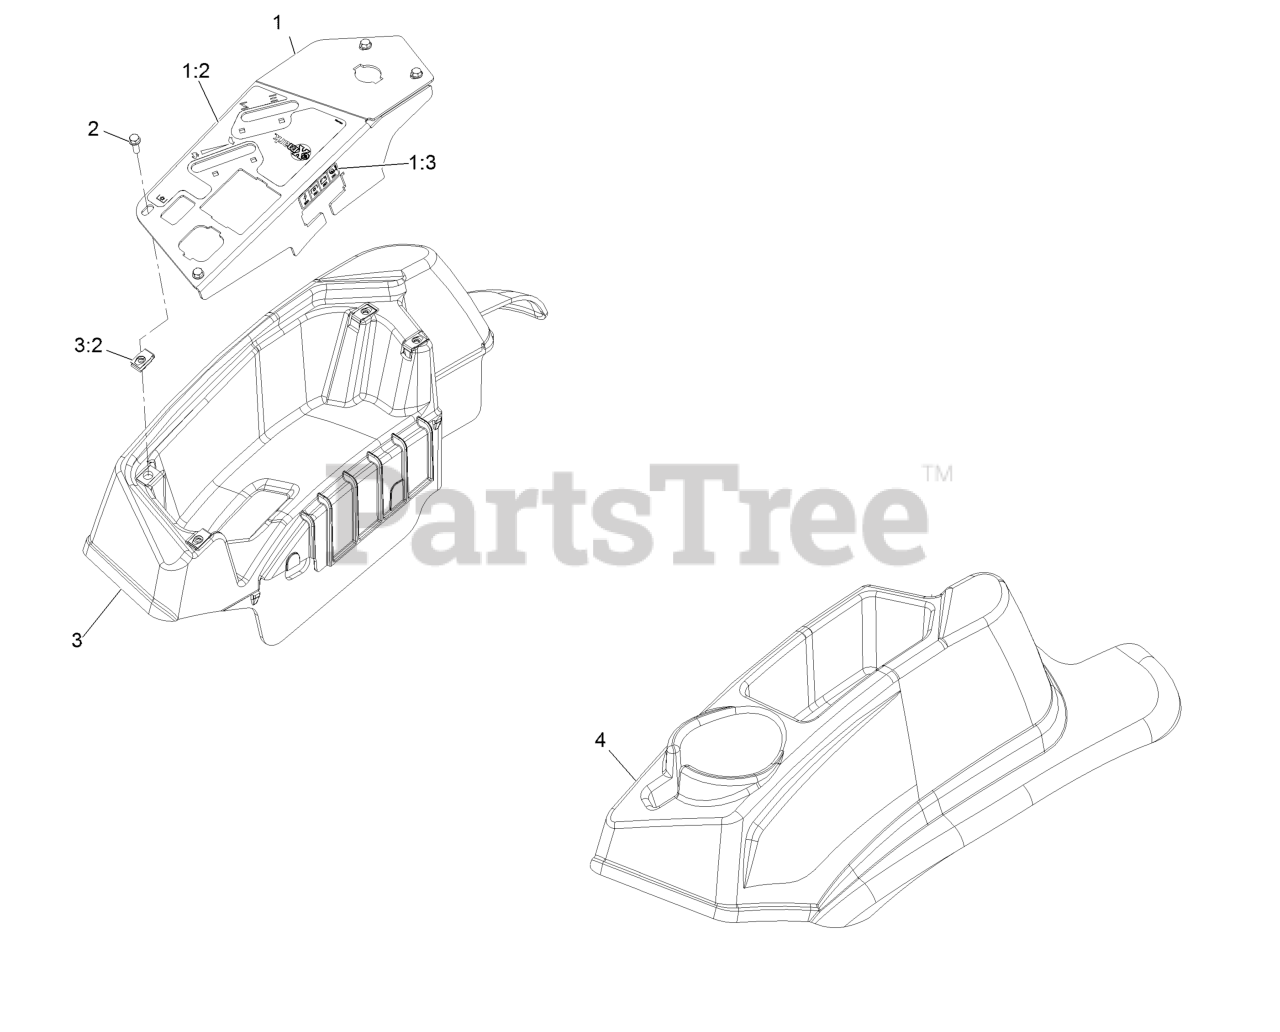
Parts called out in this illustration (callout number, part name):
1	ASM-Panel, Control W/Decal
1:2	Decal-Control Panel Non-Efi
1:3	Decal-Fuses
2	Screw-Machine 1/4-20 X 3/4
3	Console,RH As ASM
3:2	Nut-Retainer-Panel 1/4-20
4	Console, LH As
